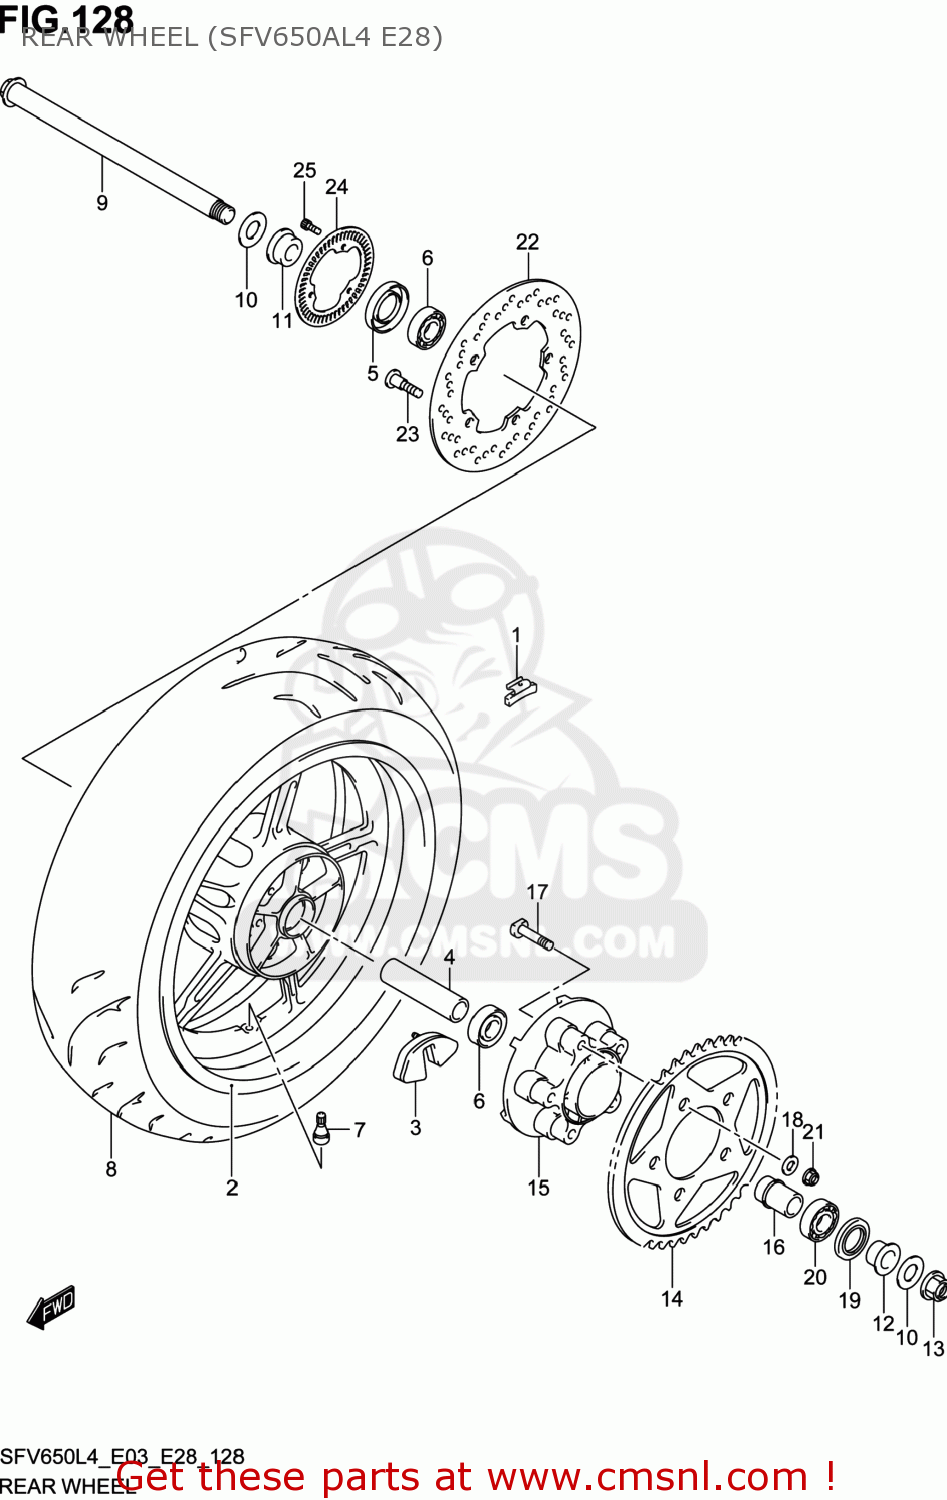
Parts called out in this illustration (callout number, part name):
1	BALANCER,WHEEL(10G)
2	WHEEL,RR(17M/CXMT5.00)
3	ABSORBER,RR HUB SHOCK
4	SPACER(20.5X28X88)
5	SEAL,OIL(28X47X7)
6	BEARING
7	VALVE ASSY,WHEEL RIM(TR412)
8	TIRE SFV650
9	AXLE,RR
10	WASHER,RR AXLE
11	SPACER,RR AXLE,R
12	SPACER,RR AXLE,L
13	NUT
14	SPROCKET,RR(46T-520)
15	DRUM,RR SPROCKET MOUNTING
16	RETAINER,RR HUB BEARING
17	BOLT(10X47)
18	WASHER(10.5X22X2.3)
19	SEAL,OIL(35X62X8)
20	BEARING(25X62X17)
21	NUT
22	DISC,RR BRAKE
23	BOLT(8X21)
24	RING,SPEED SENSOR FR(50T)
25	BOLT
